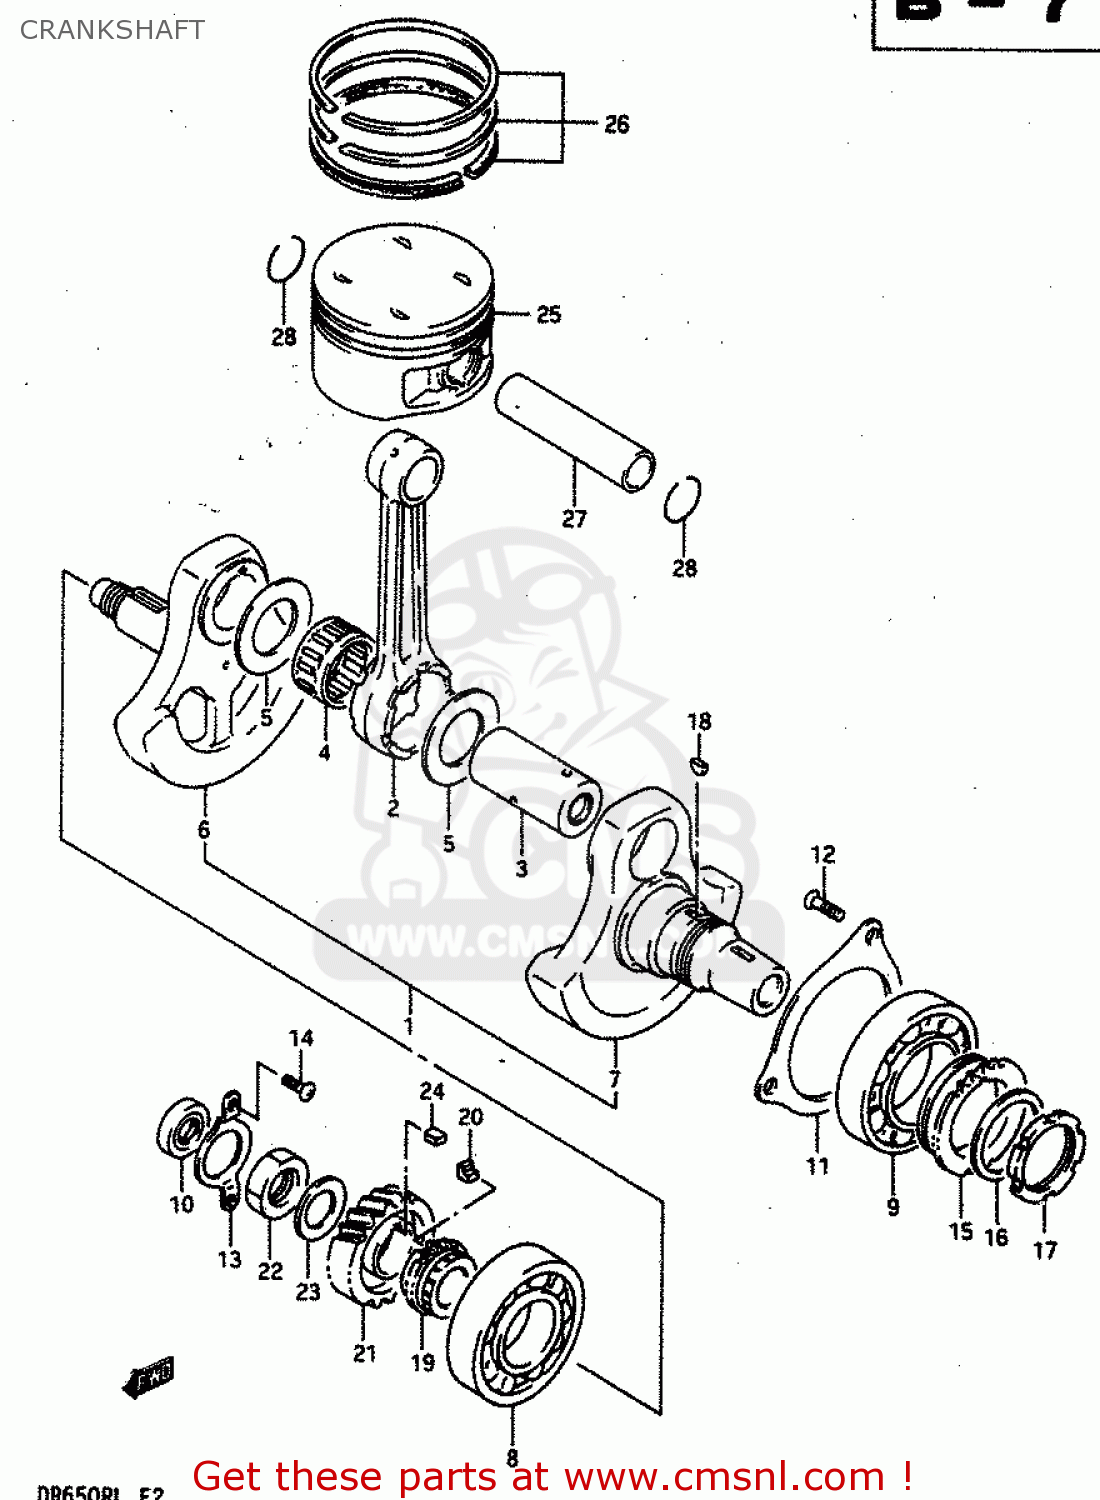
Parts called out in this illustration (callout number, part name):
1	CRANKSHAFT ASSY
2	ROD,CONNECTING
3	PIN,CRANK
4	BEARING
5	WASHER(35X55X1)
6	CRANKSHAFT,RIGHT
7	CRANKSHAFT,LEFT
8	BEARING(35X80X21)
9	BEARING
10	SEAL,OIL(16X30X6)
11	RETAINER,CRANKSHAFT BEARING,L
12	SCREW
13	RETAINER,CRANKSHAFT BEARING,R
14	SCREW
15	SPROCKET,BALANCER DRIVE
16	WASHER
17	NUT,FLYWHEEL
18	KEY
19	SPROCKET,CAM CHAIN DRIVE
20	KEY,SPROCKET
21	GEAR,PRIMARY DRIVE
22	NUT (20MM)
23	WASHER
24	KEY
25	PISTON
26	RING SET,PISTON
27	PIN,PISTON
28	CIRCLIP
